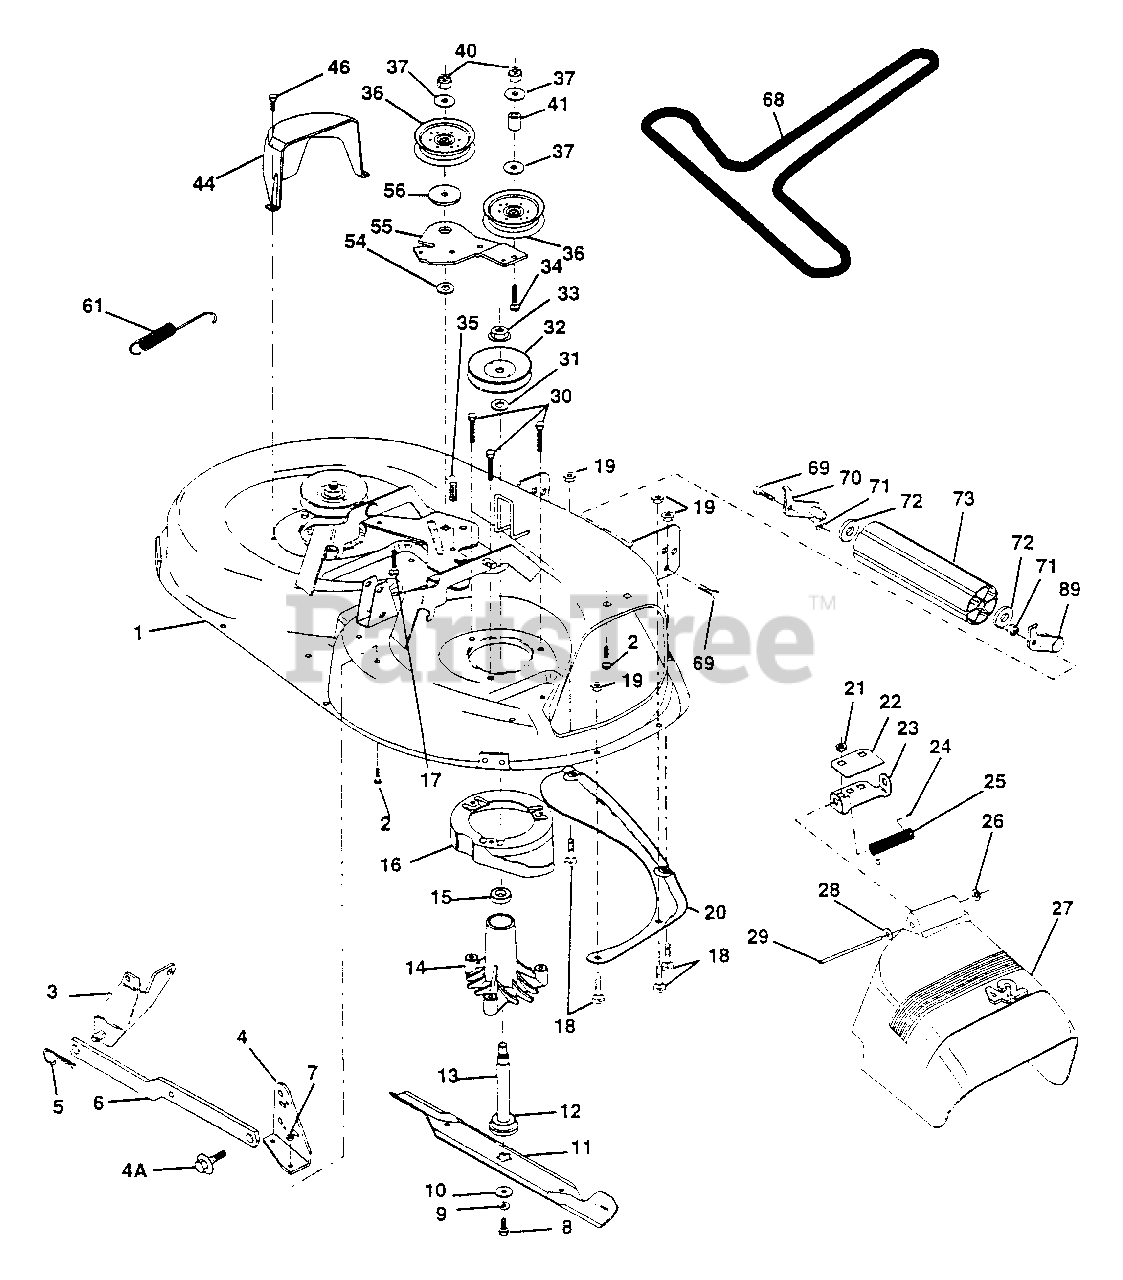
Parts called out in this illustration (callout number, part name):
1	Deck Asm MWR 42" weldment
2	Bolt Rdhd Sqnk 5/16-18unc X3/4
3	Bracket Asm Fr Sway Bar 38/42
4	Bracket Asm Deck 42"sway Bar
4A	Bolt Shoulder
5	Retainer Spring
6	Arm Suspension Rear
7	Locknut-hex W/ins 5/16-18unc P
8	Bolt 3/8-24x1 25 Gr8 Patched
9	Washer Lock Hvy 3/8 Unplated
10	Washer Hard Blade Mower Vented
11	Blade Mower High Perf 42"
12	Bearing Ball #6204 (Mandrel)
13	Shaft Asm W/lower Bearing
14	Housing Mandrel Vented(machd)
15	Bearing Ball Mandrel
16	Stripper Mower Vented
17	Bolt Rdhd Sqnk 3/8-16 X 2
18	Bolt Carr 5/16-18 X 5/8 Short
19	Locknut-hex W/ins 5/16-18unc P
20	Baffle Vortex 42
21	Nut Crown Lock 5/16-18
22	Stiffener Bracket 42" deck
23	Bracket Deflector Mower 42"
24	Cap Sleeve 80x 112 Blk Mower
25	Spring Torsion Deflector 2 52
26	Nut Push Phos & Oil
27	Shield Deflector Mower 42" Blk
28	Washer 11/32 X 5/8 X 16 Ga
29	Rod Hinge 42" 6 75 Wlg
30	Bolt 5/16-18 X 1 25 T/t
31	Washer Spacer Mower Vented
32	Pulley Mandrel 42"
33	Nut 9/16top Lock Fing Oil Dip
34	Bolt Rdhd 3/8-16uncx2-3/4 Gr5
35	Fastner Christmas Tree
36	Pulley Idler Flat 3 060
37	Washer 13/32 X 1 X 12 Ga
40	Nut Crownlock 3/8-16 Unc
41	Spacer Spring Stop Idler
44	Guard Mandrel LH Black
46	Screw Thdrol 1 /4-20 x 5/8
54	Washer Hardened
55	Arm Idler 42" mower LT/YT
56	Spacer Retainer Pm Mower
61	Spring Return
68	V-Belt Mower 42" 92 40
69	Bolt Fin Hex 3/8-16unc X 1
70	Bracket Asm Noseroller LH
71	Nut Crownlock 3/8-16 Unc
72	Washer 17/32 X 7/8 X 16 Ga
73	Roller Nose 38 & 42
89	Bracket Asm Noseroller RH
